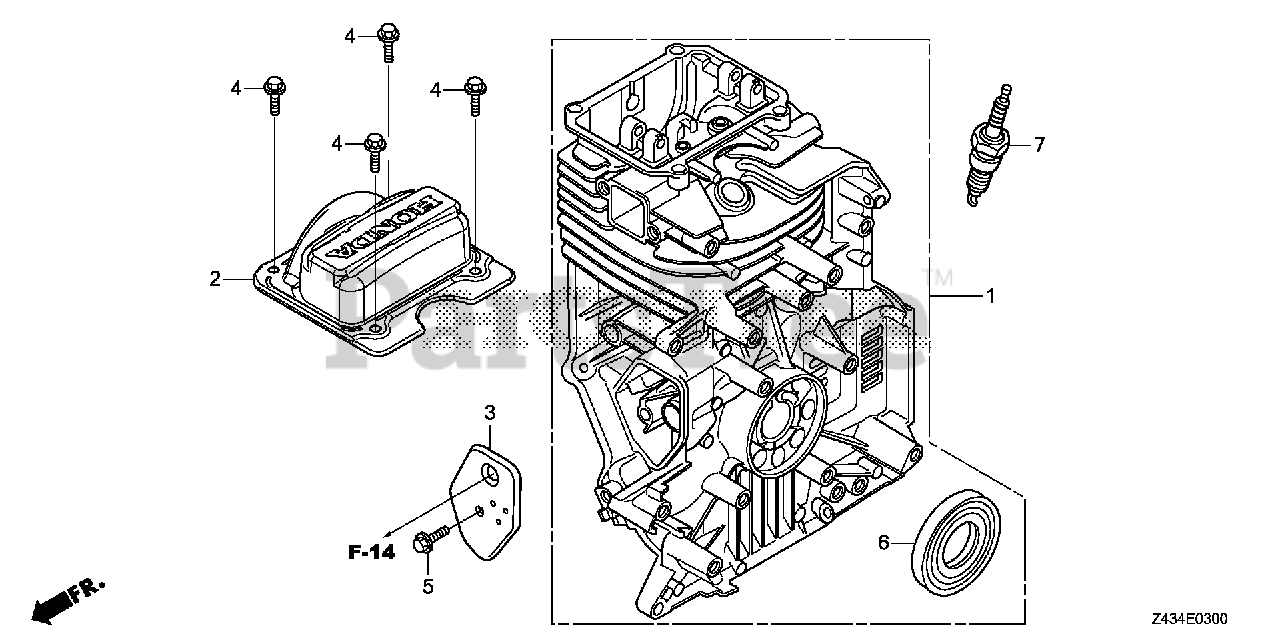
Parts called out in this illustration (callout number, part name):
1	CYLINDER ASSY.
2	COVER, CYLINDER HEAD
3	COVER, BREATHER (Honda Code 5580006). (BREATHER VALVE ASSY.)
4	BOLT, FLANGE (6X12) (CT200)
5	BOLT, FLANGE (6X14)
6	OIL SEAL (25.4X62X6)
7	SPARK PLUG (BPR5ES) (NGK)
7	SPARK PLUG (BPR6ES) (NGK)
